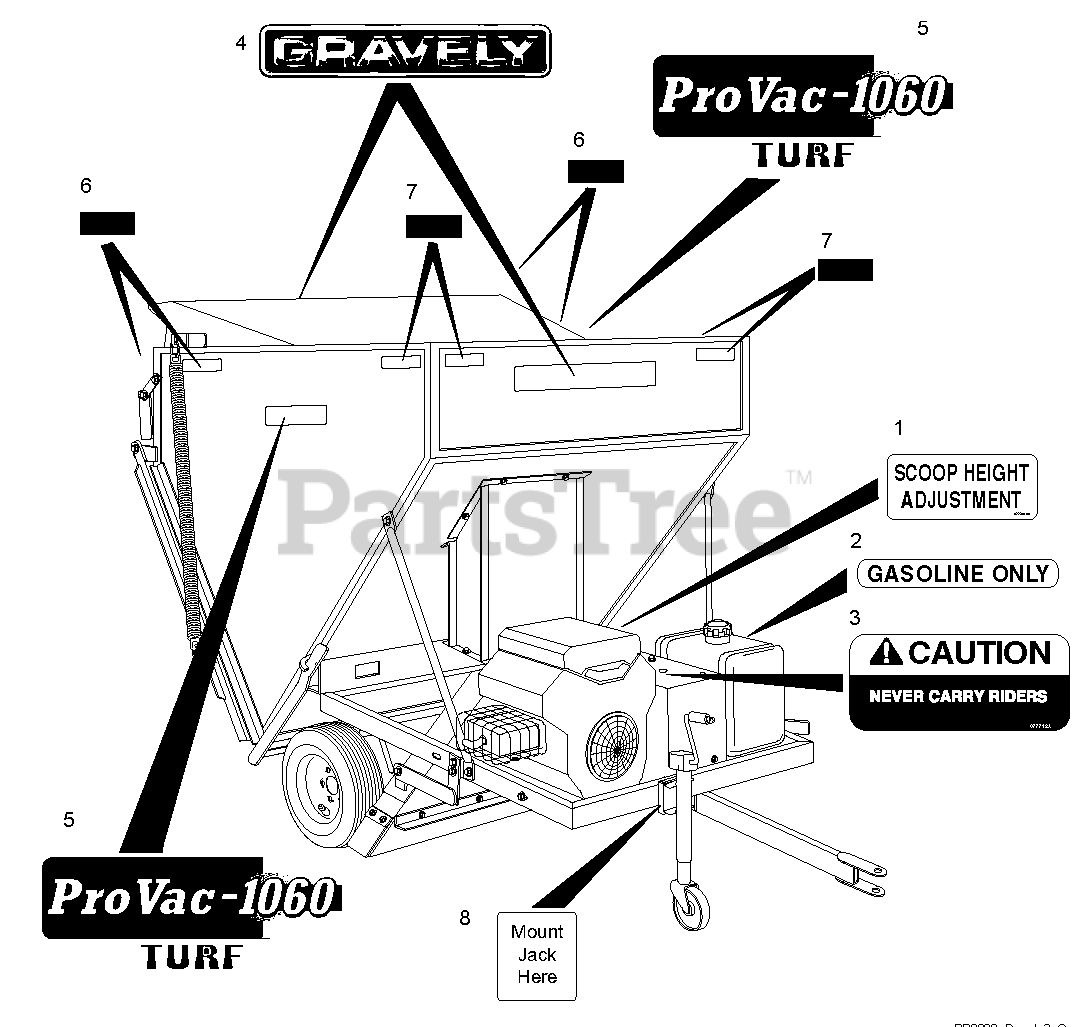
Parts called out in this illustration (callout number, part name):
1	Decal, Scoop Height Adjustment
2	Decal, Gasoline Only
3	Decal, No Riders
4	Decal, 15" Gravely Logo
5	Decal, Product, Pro Vac 1060, 15"
6	Reflector, Red
7	Reflector, Amber
8	Decal, Mount Jack Here
